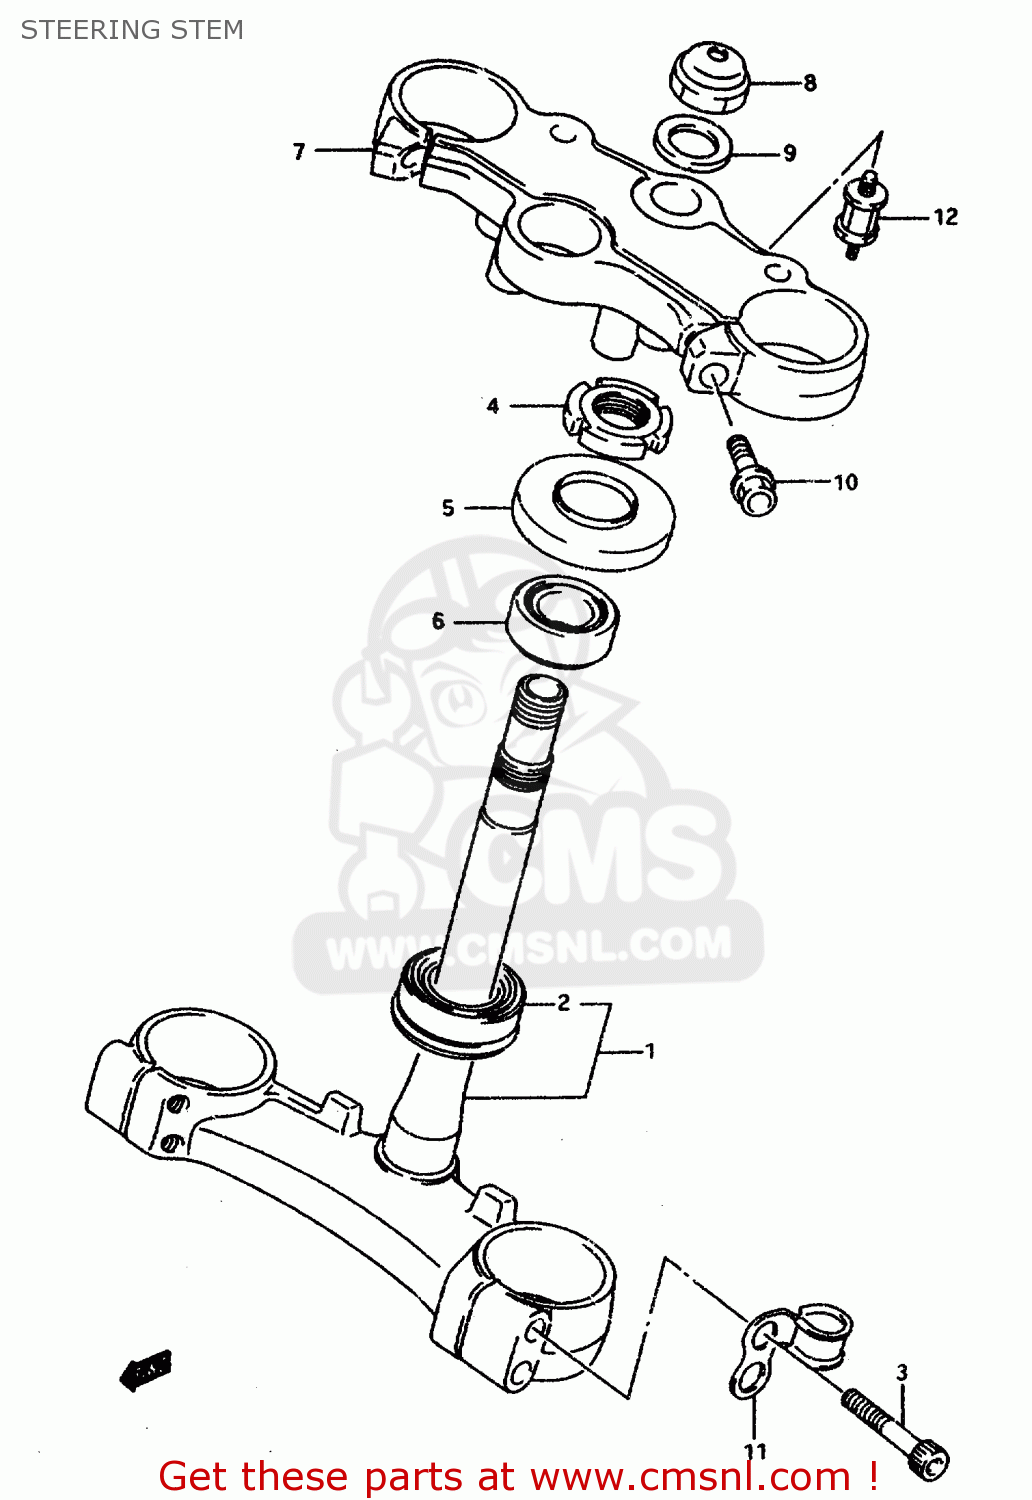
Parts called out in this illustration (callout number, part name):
1	STEM,STEERING
2	BEARING(30X55X17)
3	BOLT
4	NUT,STEERING STEM(25X44X10)
5	SEAL,OIL(34X69X11.9)
6	BEARING(25X47X15)
7	HEAD,STEERING STEM
8	NUT
9	WASHER(22.5X32X1.6)
10	BOLT
11	GUIDE,SPEEDOMETER CABLE
12	BOLT,SPEEDOMETER CUSHION
